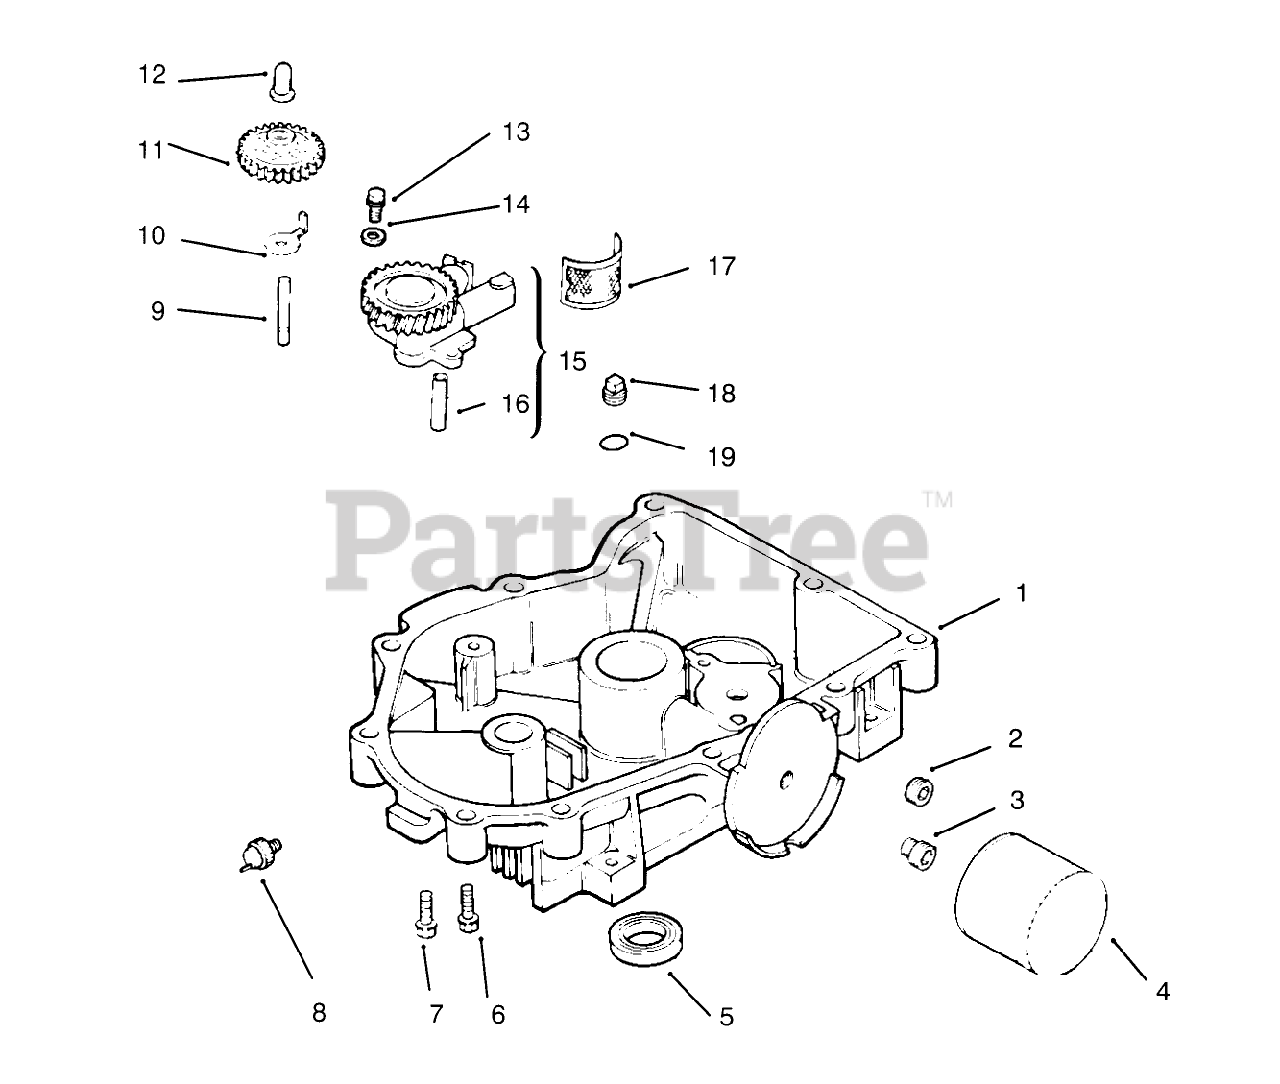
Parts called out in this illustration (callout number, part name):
1	Oil Pan (Only On: 72103)
2	Plug-HS 3/8 NPTF (Only On: 72103, 72083)
3	Nipple-Oil Filter
4	Filter-Oil
5	Seal-Oil
6	Screw M8x1.25x45 (Only On: 72103, 72083)
8	Switch-Oil Pressure
9	Shaft-Govenor Gear
10	Tab-Locking
11	Governor Gear ASM (Only On: 72103)
12	Pin-Governor
15	Oil Pump ASM INCL 16 (Only On: 72103)
16	Tube-Oil Pickup (Only On: 72103, 72083)
17	Screen-Oil Pickup (Only On: 72042, 72063, 72062, 72043)
